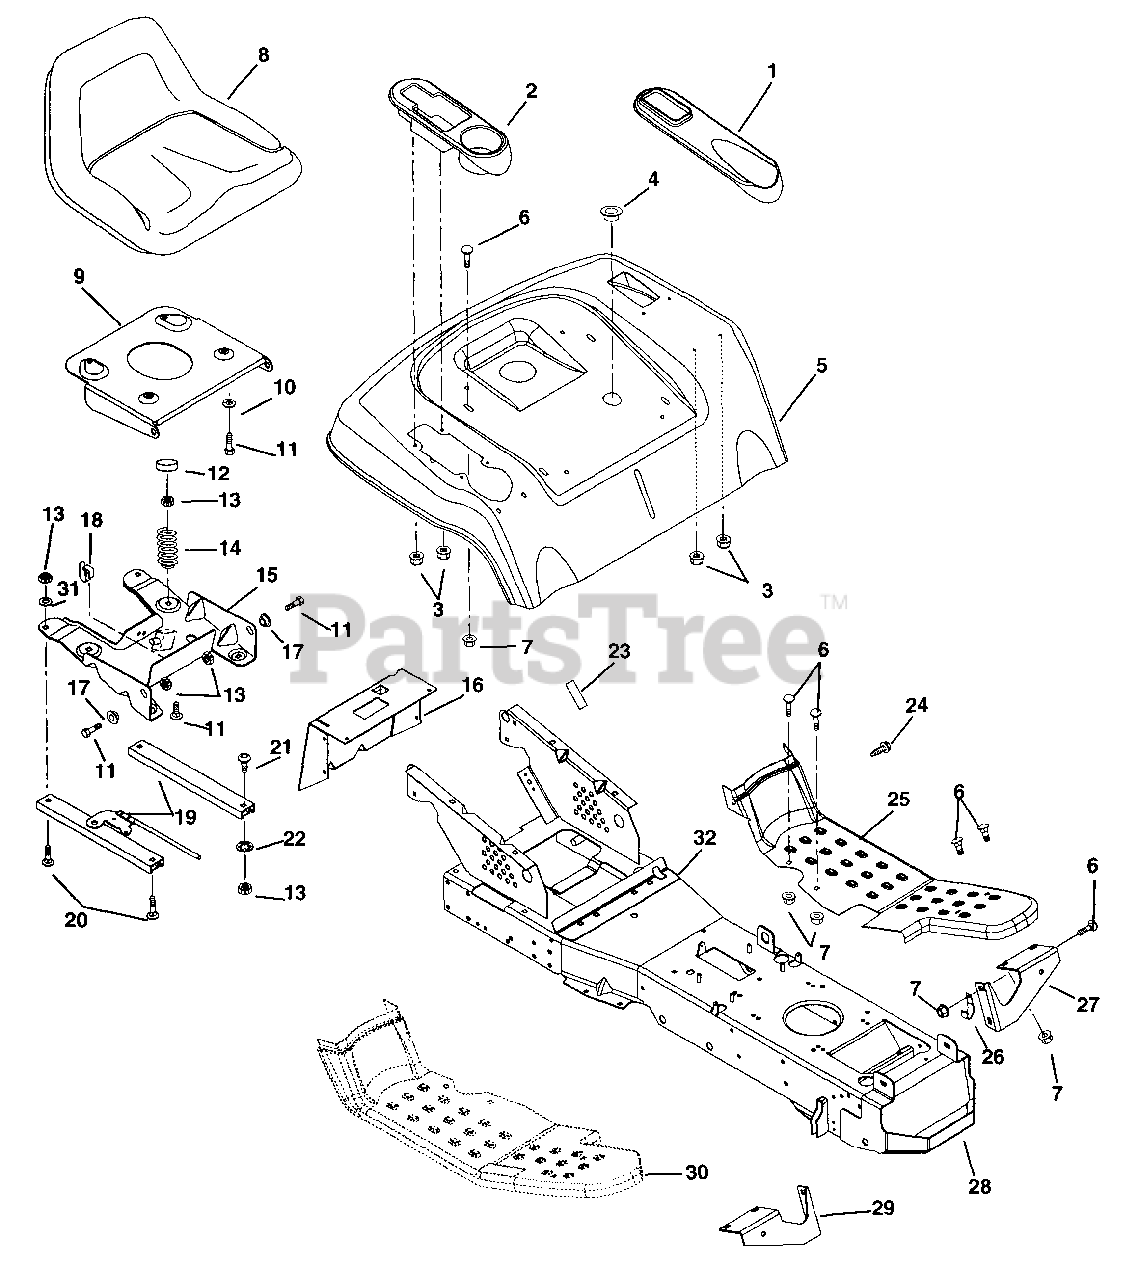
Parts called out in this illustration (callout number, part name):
1	Insert - Lift
2	Holder-Beverage
3	Nut-Self-Threading
4	Snap Bushing
5	Rear Deck
6	Bolt-Round Head Square Neck .312-18 x .62
7	Nut-Locking Flange .312-18
8	Seat
9	Seat Pivot Plate
10	Washer-Lock .312 x .097
11	Bolt-Hex .31-18 x .75 Grade 5
12	Tube Cap
13	Nut-Locking-Center .312-18
14	Spring-Compression .148 x 1.23 x 2.41
15	Seat Box
17	Bushing-Flange .325 x .465 x .333 x .685
18	Clip-Harness
19	Seat Slides
20	Bolt-Round Head Square Neck .31-18 x .75 Grade 2
21	Screw-Cap Button Head .31-18 x .50
22	Washer-Lock-Internal .31
23	Pad-Foam
24	Screw-Tapping .31-18 x .50 Hex Washer Head
25	Footrest-Left Hand
26	J-Clamp
27	Brace-Foot Rest Left Hand
28	Frame-Main
29	Brace-Foot Rest Right Hand
30	Footrest-Right Hand
31	Washer-Locking .313
32	Plate-Frame Reinforcing
